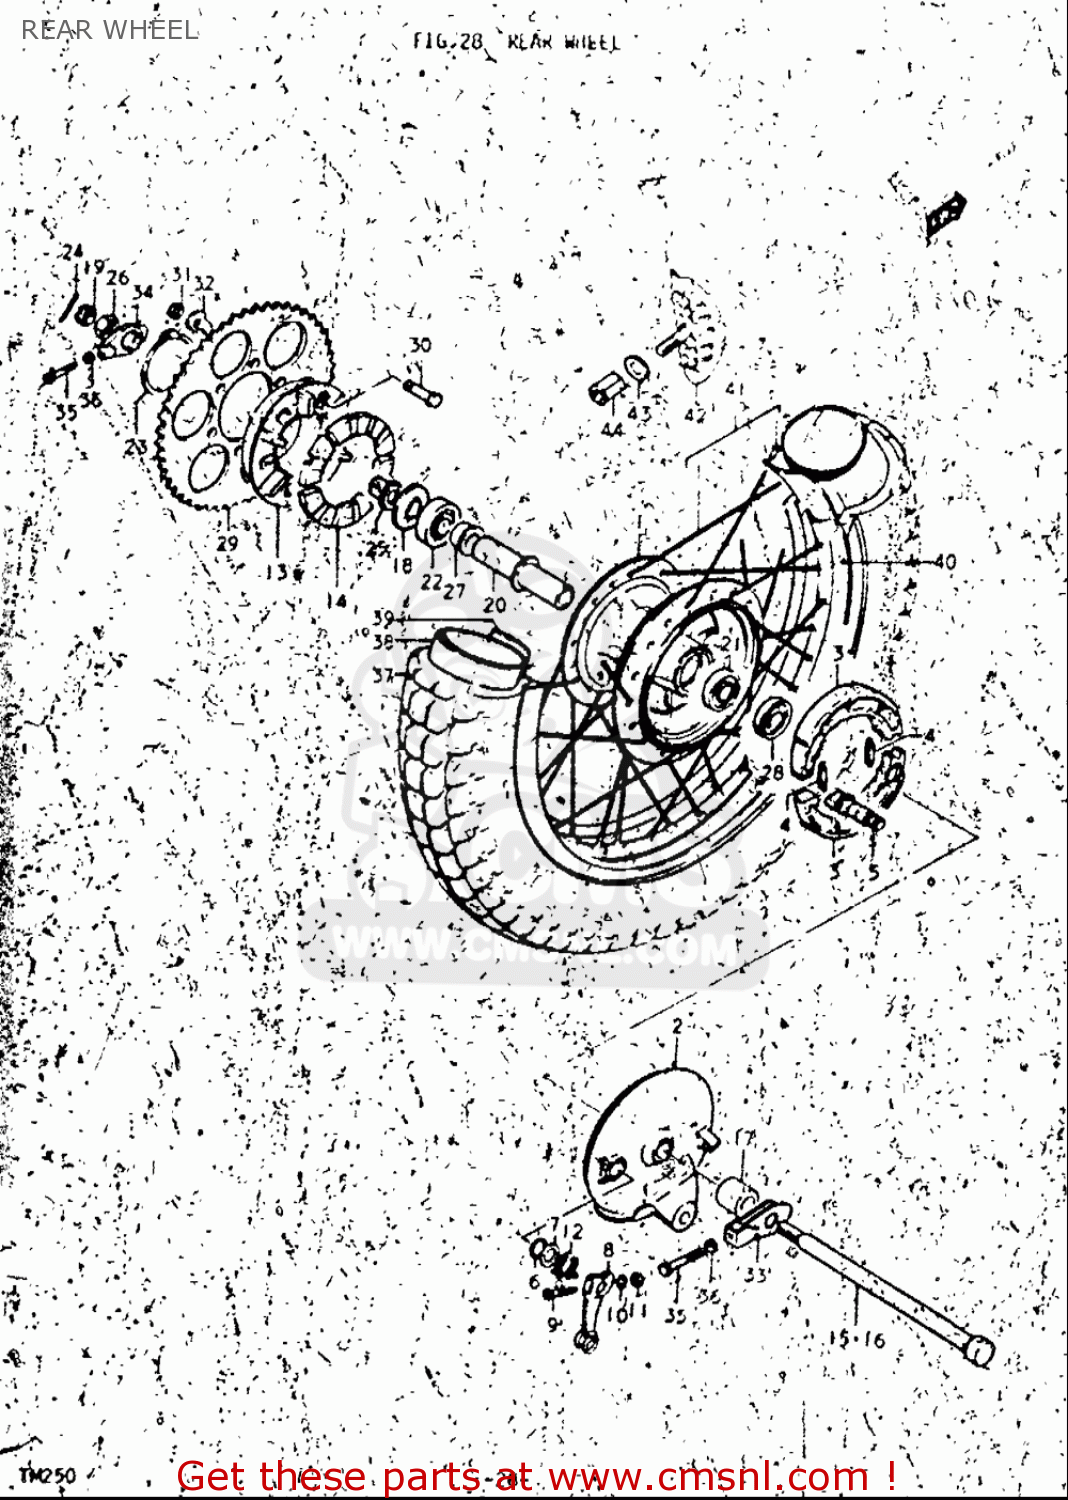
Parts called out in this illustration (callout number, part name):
3	SHOE SET,BRAKE (NAS)
4	SPRING,BRAKE SHOE
5	CAM,BRAKE
6	O RING(D:2.4,ID:14.8)
7	WASHER(15.5X24X1.6)
9	BOLT
10	WASHER
11	NUT
12	SPRING
14	ABSORBER,RR WHEEL HUB SHOCK
15	AXLE,REAR
16	AXLE,REAR
19	NUT
20	SPACER,REAR HUB BEARING
21	BEARING(15X42X13)
22	BEARING
23	CIRCLIP
24	PIN 30X40
25	SPACER,REAR AXLE,LEFT
26	NUT
27	SPACER,REAR HUB BEARING
30	BOLT(8X33.5)
31	NUT
32	WASHER
33	ADJUSTER,CHAIN,R
34	ADJUSTER,CHAIN,L
36	NUT
39	PROTECTOR,INNER TUBE
41	SPOKE SET,RR
42	STOPPER,BEAD(1.85)
43	WASHER
